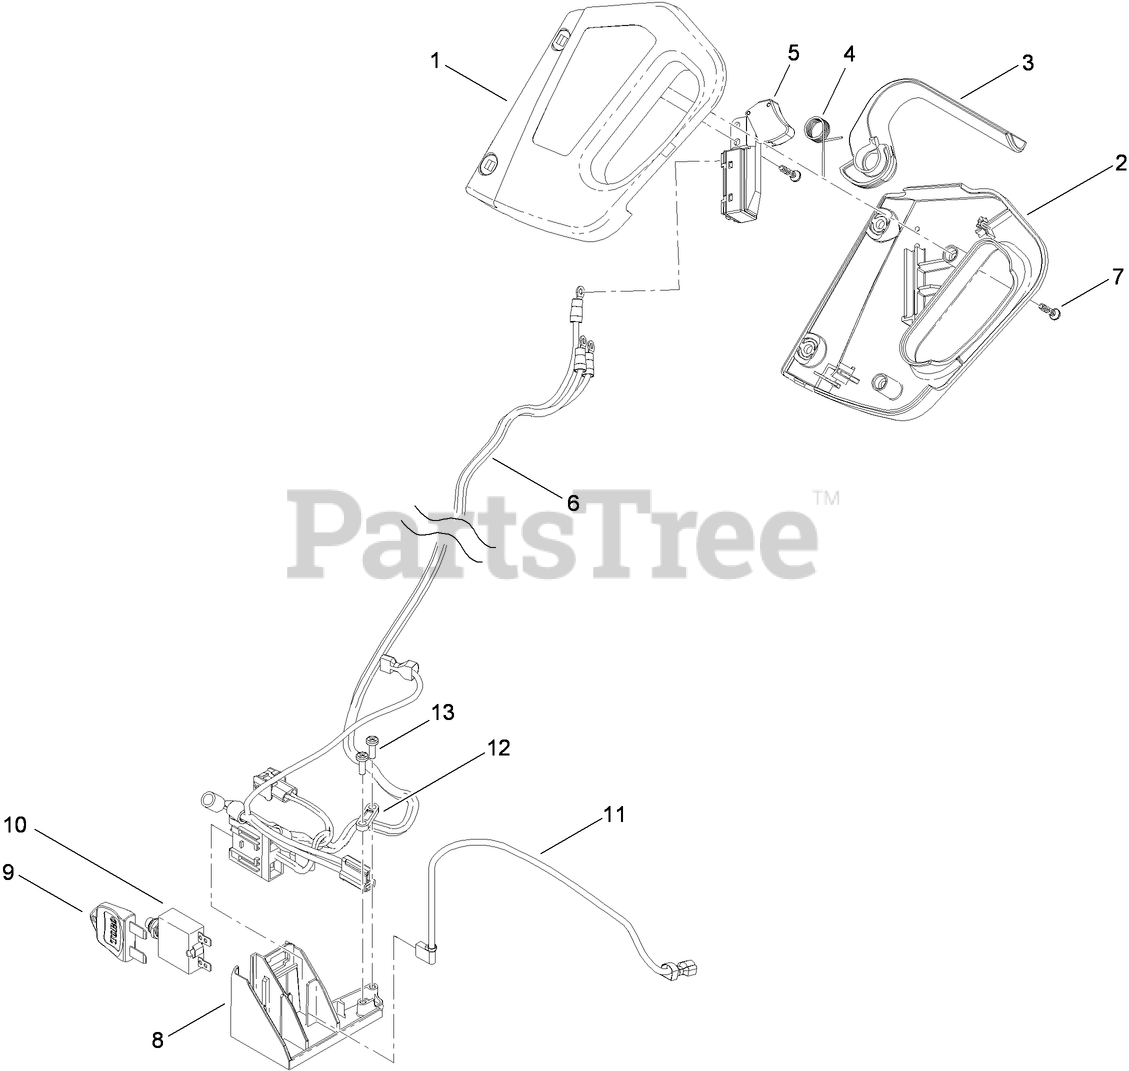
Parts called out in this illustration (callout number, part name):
1	HOUSING-SWITCH, LH
2	HOUSING-SWITCH, RH
3	LEVER-SWITCH
4	SPRING-TORSION, LEVER
5	SWITCH-36V, MARQUARDT
6	HARNESS-WIRE
7	SCREW-PPH
8	HOUSING-TERMINAL
10	CIRCUIT BREAKER
11	HARNESS-WIRE (JUMPER)
12	CLAMP-HARNESS
13	SCREW-PPH
